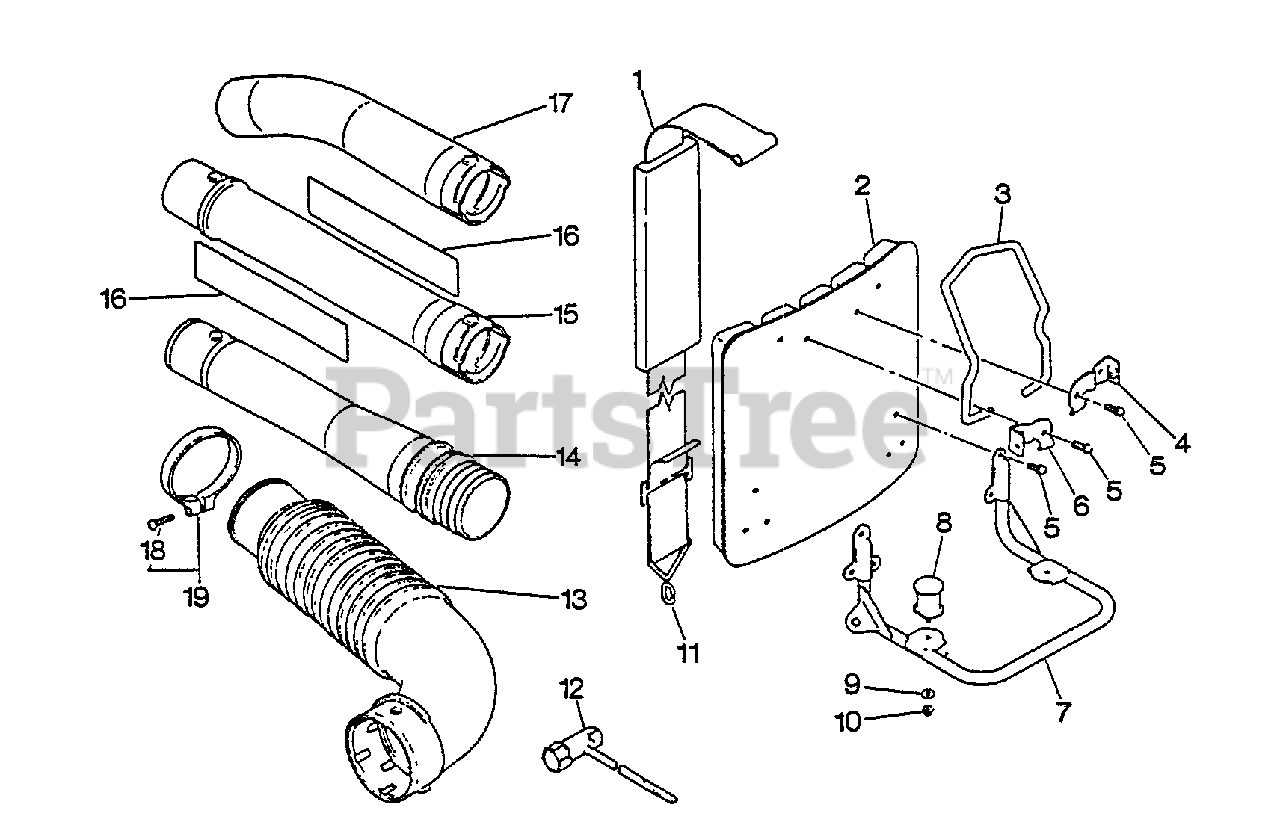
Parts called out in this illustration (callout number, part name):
1	BACKPACK STRAP ASSY
2	CUSHION, BACKPACK
5	SCREW - 5X10
6	BRACKET, HANGER
7	STAND
9	WASHER - 6.5
10	NUT - 6 -- FLANGE
11	RING, STRAP
12	T-WRENCH - 10X19mm
13	TUBE, BLOWER - FLEXIBLE
14	TUBE, BLOWER - SWIVEL
15	TUBE, BLOWER - STRAIGHT
16	LABEL - ECHO
17	TUBE, BLOWER - CURVED
18	SCREW - 5X20
19	CLAMP KIT
